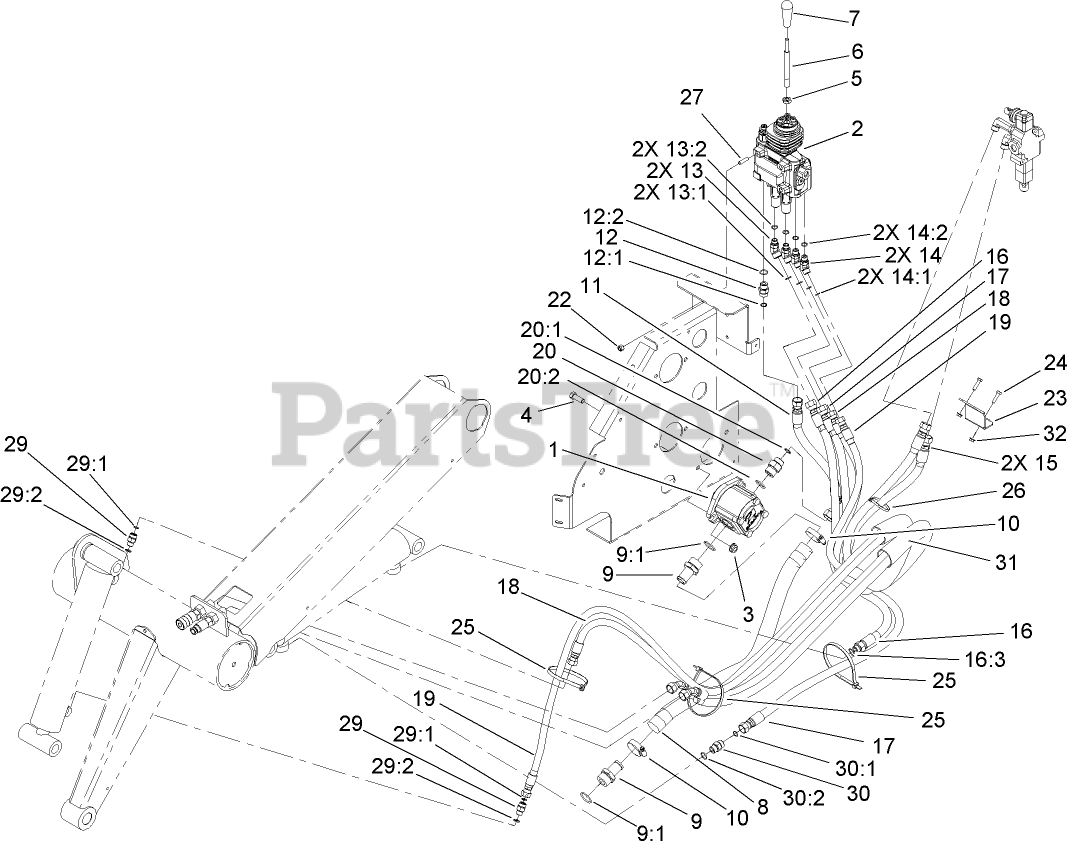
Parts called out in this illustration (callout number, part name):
1	PUMP-GEAR
2	VALVE-LOADER
3	NUT-HF
4	SCREW-HH
6	SHAFT-HANDLE, LIFT/TILT
7	KNOB-TAPERED
8	HOSE-HYD, SUCTION
9	FITTING-STR
9:1	O-RING
11	HYD HOSE ASM
12	FITTING-STRAIGHT
12:1	O-RING
12:2	O-RING
13	ADAPTER
13:1	O-RING
13:2	O-RING
14	FITTING-ELBOW, 45 DEG
14:1	O-RING
14:2	O-RING
15	HYD HOSE ASM
16	HYD HOSE ASM
16:3	O-RING
17	HYD HOSE ASM
18	HYD HOSE ASM
19	HYD HOSE ASM
20	FITTING-STRAIGHT
20:1	O-RING
20:2	O-RING
22	NUT-LOCK, NI
23	CLAMP-HOSE
24	SCREW-HH
25	TIE-CABLE
26	TIE-CABLE
29	FITTING-STRAIGHT
29:1	O-RING
29:2	O-RING
30	FITTING-STRAIGHT
30:1	O-RING
30:2	O-RING
31	SLEEVE-HOSE
32	NUT-HF
